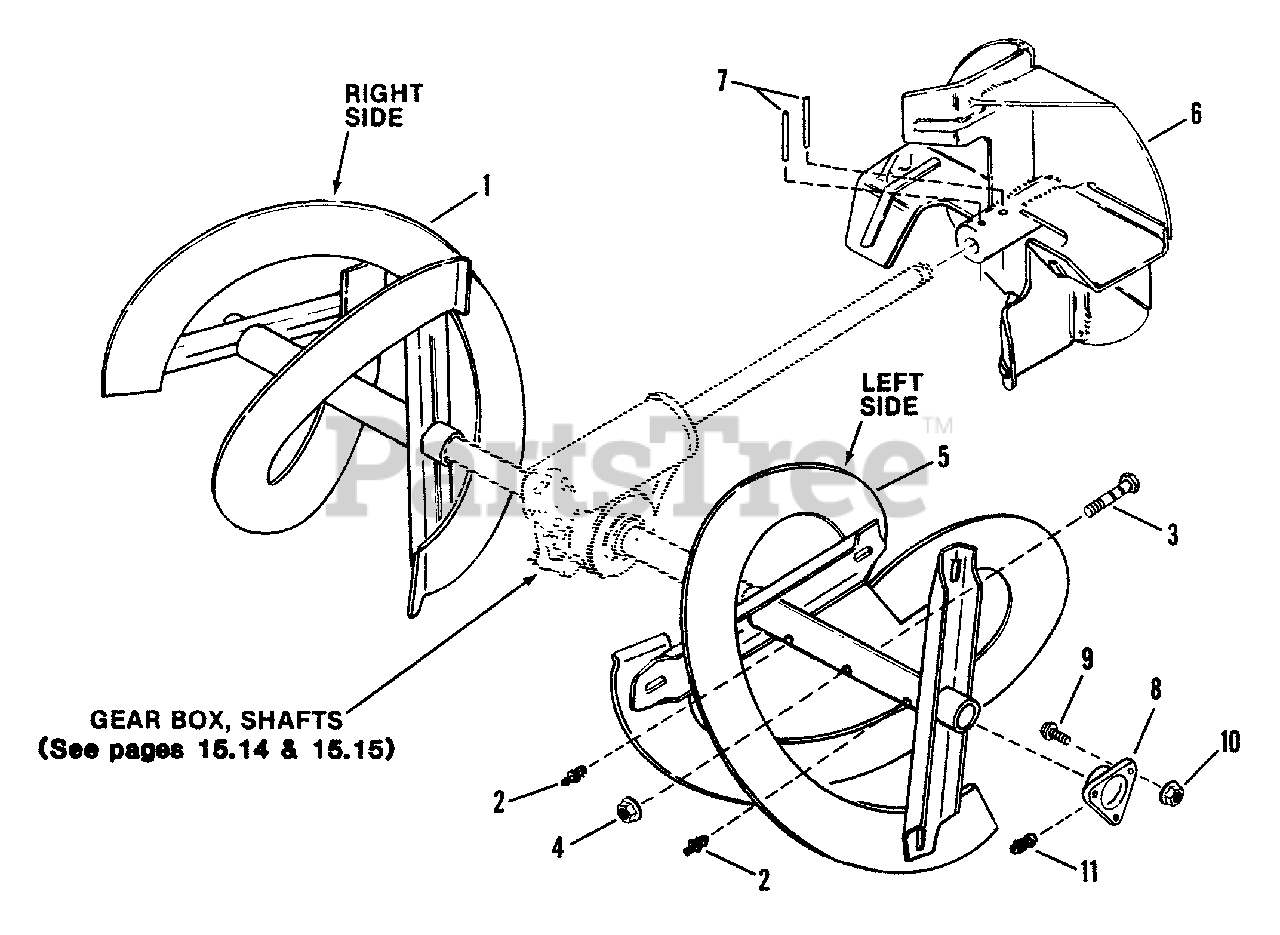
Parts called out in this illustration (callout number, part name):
1	AUGER, Right Side
2	LUBE FITTING, Straight (press-fit for .187 dia. Hole)
3	BOLT, 5/16-18 x 1-7/8" Shear
4	LOCKNUT, 5/16-18 Hex Flange
5	AUGER, Left Side
6	FAN, Impeller
7	PIN, 1/4 x 1-1/2" Roll
8	BEARING, Auger Shaft
9	BOLT, 1/4-20x5/8 Hex Flange Lock
10	NUT, 1/4-20 Hex Flange
11	FITTING, Grease (Straight Press Fit .187" Hole, .25" Deep)
